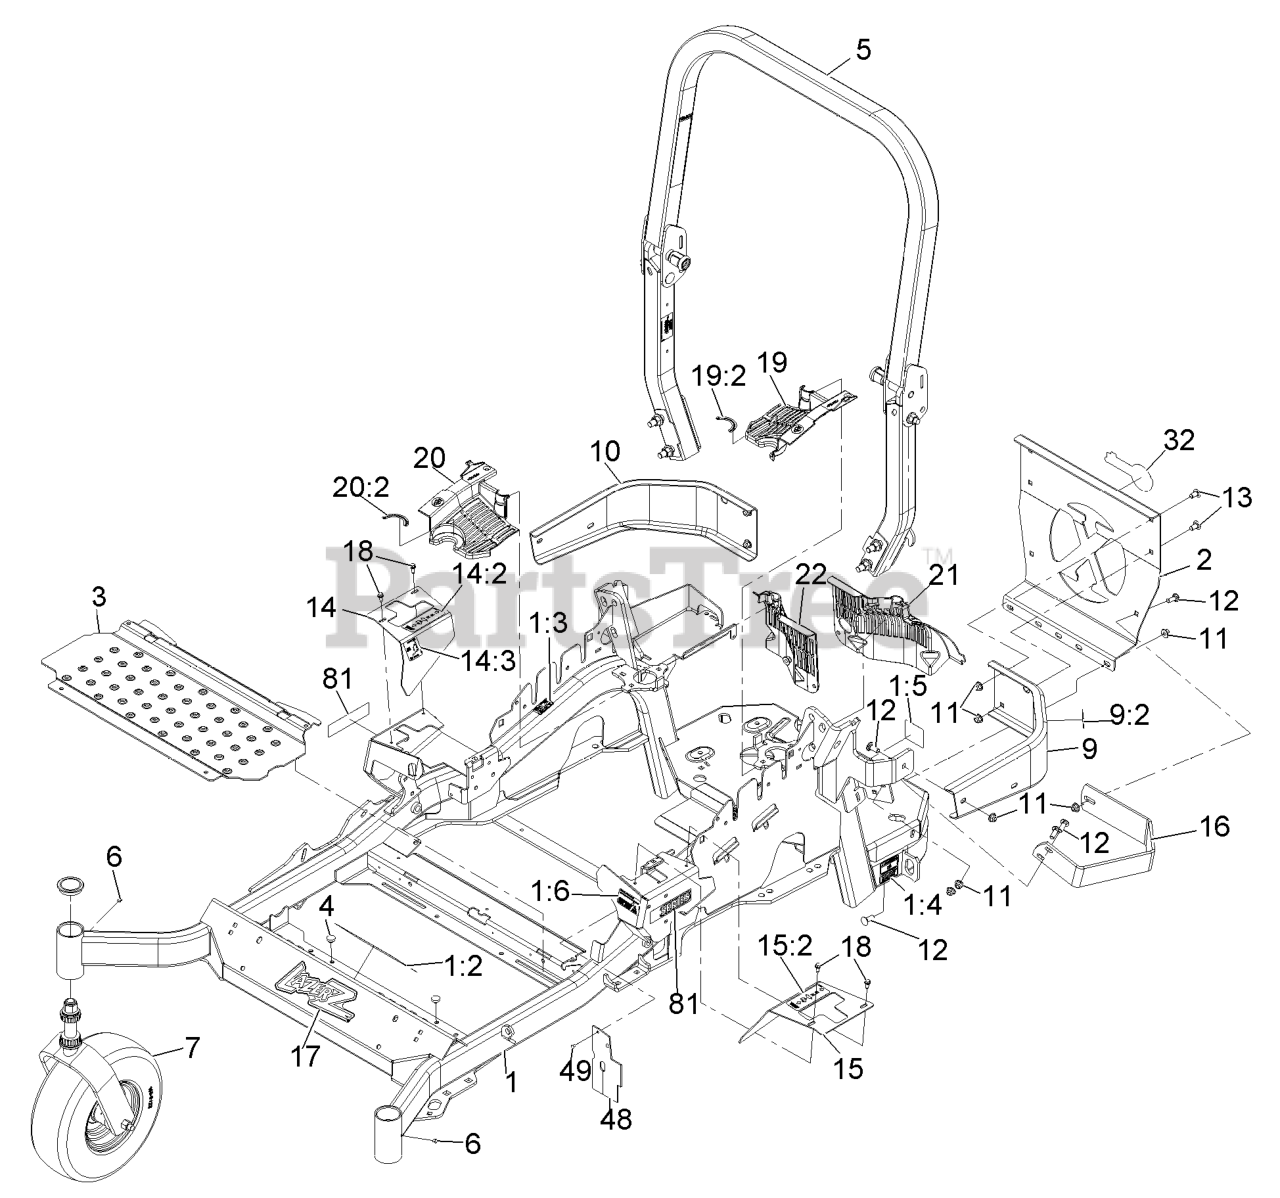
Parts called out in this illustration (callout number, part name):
1	MAIN FRAME ASM
1:2	DECAL-SLOPE
1:3	DECAL-CAUTION
1:4	DECAL-BELT DRIVE
1:5	DECAL-SPARK ARRESTER
1:6	DECAL-FUEL FILL
2	PLATE,REAR GUARD
5	ASM,ROPS SERVICE EXMARK
7	Caster Wheel Asm
9	LH BUMPER ASM
9:2	DECAL-CAUTION
10	BUMPER-RH
11	NUT-HF, NI
12	SCREW-CARR
13	SCREW-CARR
14:2	DECAL-MOTION CONTROL
15	LH MOTION CONTROL COVER ASM
15:2	DECAL-MOTION CONTROL
17	DECAL,LAZER MODEL
18	SCREW-HWH
19	LH HYDRO GUARD ASM
19:2	DECAL-HYDRO OIL
20	RH HYDRO GUARD ASM
20:2	DECAL-HYDRO OIL
21	GUARD-HYDRO REAR, LH TRIM
22	GUARD-HYDRO, REAR (RH)
48	DEFLECTOR-AIR FLOW
49	RIVET-POP
81	DECAL-X-SERIES
